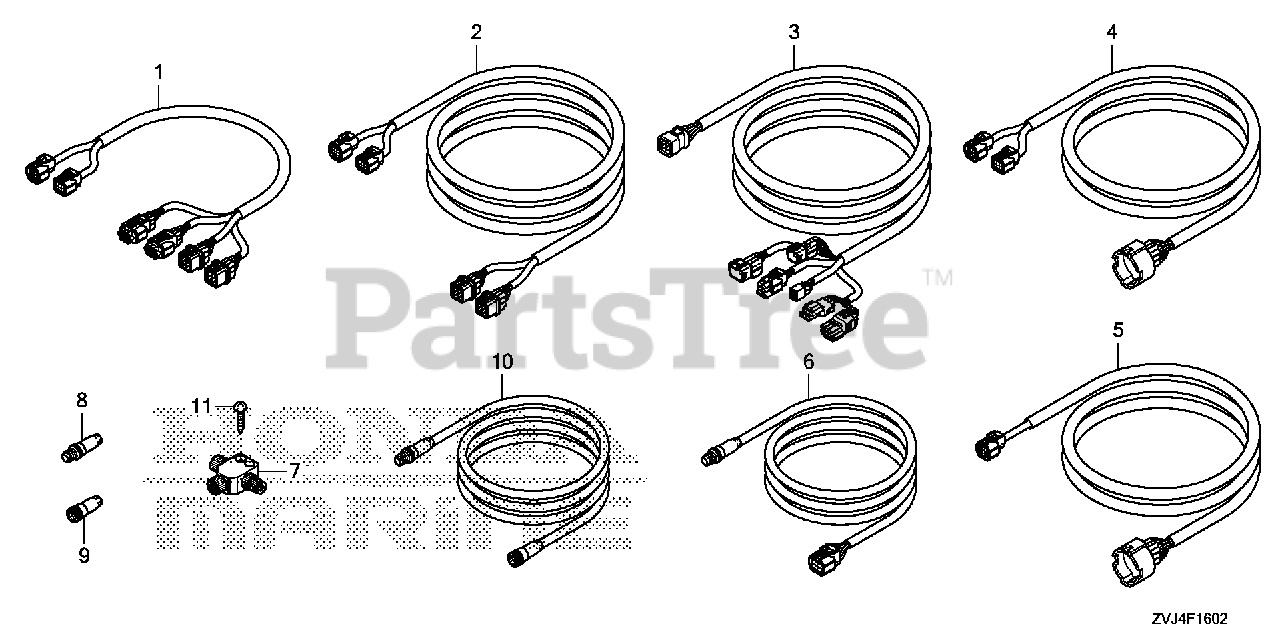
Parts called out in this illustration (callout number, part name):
1	CABLE ASSY., BRANCH
2	CABLE ASSY., TRUNK (30FT) (DBW)
3	CABLE ASSY., PANEL INDICATOR (30FT)
5	CABLE ASSY., ENGINE DROP (6FT)
6	CABLE ASSY., INTERFACE (16FT)
6	CABLE ASSY., INTERFACE (6FT)
7	CONNECTOR (T)
8	TERMINATOR (M)
9	TERMINATOR (F)
10	CABLE ASSY., NETWORK (6FT)
10	CABLE ASSY., NETWORK (49FT)
11	SCREW, TAPPING (4X25)
